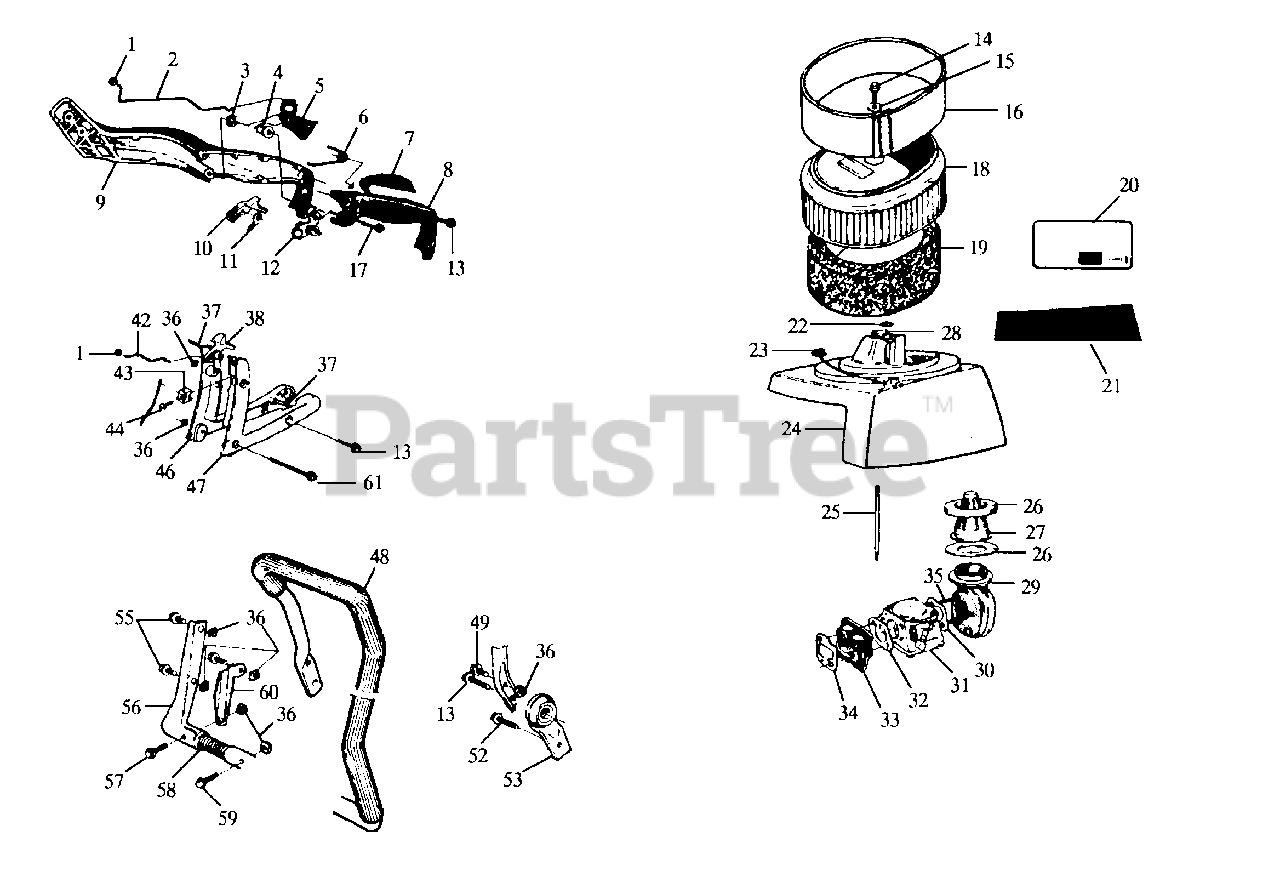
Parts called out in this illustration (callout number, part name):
1	Lockwasher
2	Throttle Rod
5	Throttle Control
7	Throttle Catch
8	Handle
9	Right Handle
10	Stop Button
11	Contact Spring
16	Filter Cover
19	Air Filter
23	Plug
24	Cylinder Cover
26	Seal Kit
27	Filter w/Seal
29	Intake Pipe
31	Carburetor
32	Gasket
33	Insulator Flange
34	Gasket
36	Square Nut
37	Spring Pin
38	Choke Button
42	Choke Rod
43	Cable Holder
44	Screw
46	Right Bracket
47	Left Bracket
48	Front Handle
53	Absorber
55	Bolt w/Washer
58	Absorber
